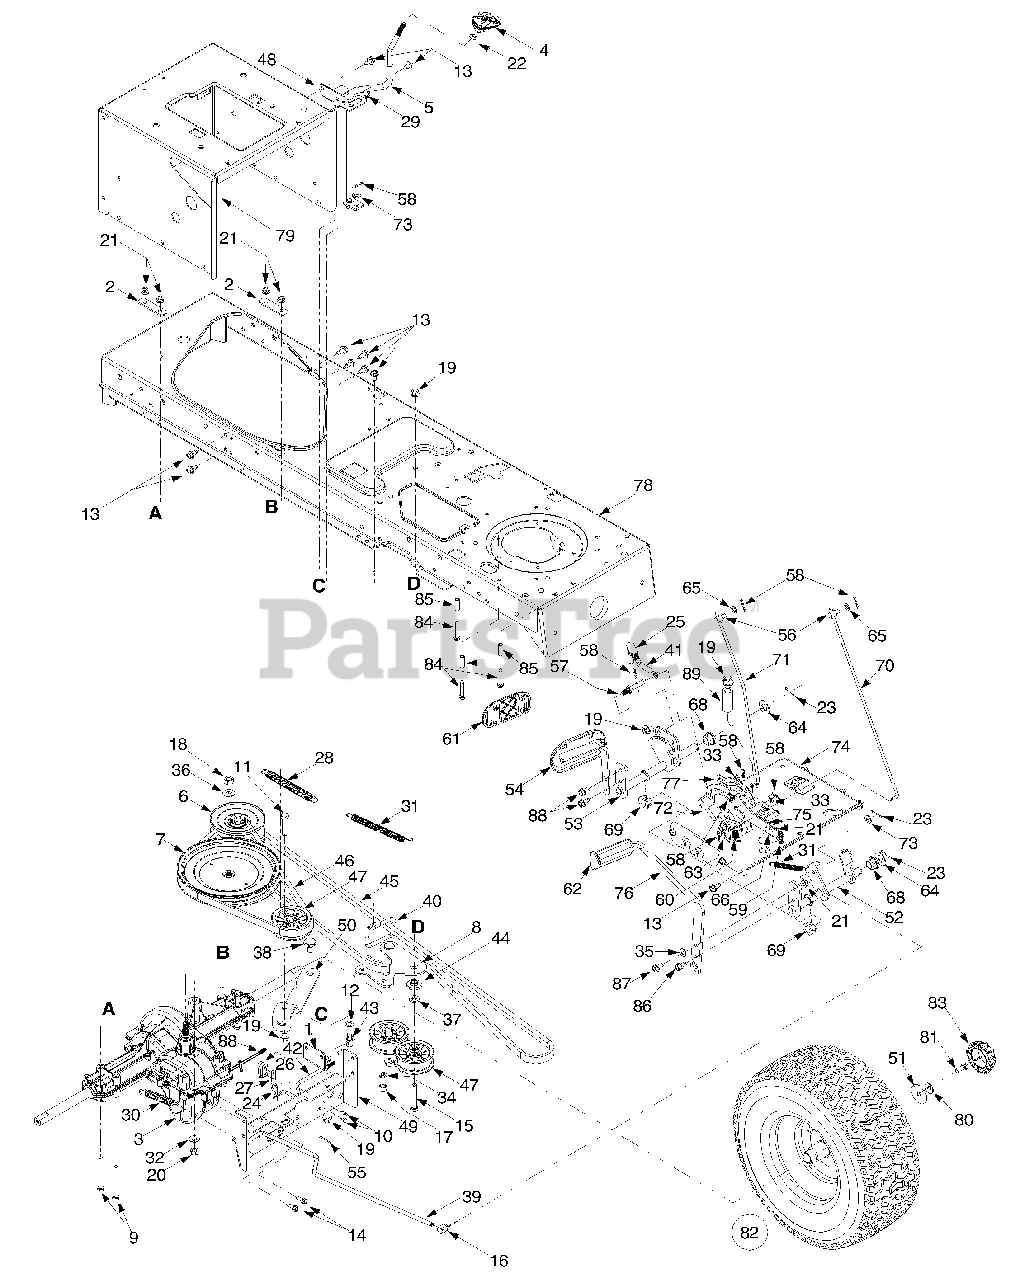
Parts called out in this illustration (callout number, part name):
1	Shift Lever Support
2	Transaxle Mounting Bracket
3	Single-speed Transmission Assembly
4	Shifter Knob
5	Shift Lever
6	Variable-speed Pulley Assembly
7	Transmission Pulley, 8.5 x .5-36
7	Pulley Hub
8	Double-idler Bracket
9	Hex Cap Screw, 5/16-18 x 2.75
10	Self-tapping Screw, #8-18 x .5
11	Hex Cap Screw, 3/8-16 x 1.75
12	Flat Washer, .51 x 1.0 x .060
13	Self-tapping Screw, 5/16-18 x .625
14	Self-tapping Screw, 1/4-20 x .75
15	Hex Cap Screw, 3/8-16 x 2.25
16	Ferrule, 5/16-18
17	Hex Nut, 3/8-24
18	Hex Nut, 7/16-20
19	Flange Lock Nut, 3/8-16
20	Hex Nut, 3/8-16
21	Flange Lock Nut, 5/16-18
22	Jam Nut, 3/8-16
23	Cotter Pin
24	Internal Cotter Pin
25	Ball Joint
26	Short Spring Switch
27	Insulator Nut Plate
28	Extension Spring, .62 Dia. x 6.12
29	Compression Spring Clip
30	Extension Spring, .59 OD x 4
31	Extension Spring, .50 Dia. x 6.37
32	Bell Washer, .401 x .87 x .063
33	Flat Washer, .385 x .62 x .063
34	Lock Washer, 3/8
35	Flat Washer, .344 x .750 x .120
36	Bell Washer, .45 x 1.0 x .602
37	Flat Washer, .407 x .812 x .135
38	Shoulder Screw, .625 x .217
39	Brake Rod
40	Belt Guard
41	Idler Adjustment Rod, 3/8
42	Shift Rod
43	Adjustment Ferrule, 1/4-20 x 1.0
44	Shoulder Spacer, .38 ID
45	Lower Drive Belt
46	Upper Drive Belt
47	Flat Idler, 2.75 OD
48	Speed Control Rod Bracket
50	Idler Bracket
51	Flat Washer, .350 x 1.59 x .062
52	Brake Control Assembly
53	Speed Control Assembly
54	Drive Pedal Assembly
55	Cotter Pin, 1/8 x 1.25
56	Ferrule, 1/4-20
57	Pin, 3/8-16 x 2.43
58	Cotter Pin
59	Compression Spring, .34 OD x 1.0
60	Extension Spring, .50 OD x 1.41
61	Drive Pedal Pad
62	Brake Pedal Pad
63	Flat Washer, .281 x .5 x .063
64	Flat Washer, .64 x 1.24 x .06
65	Flat Washer, .344 x .062 x .03
66	Shoulder Screw, .437 x 1.62
67	Shoulder Screw, .5 x .434
68	Hex Flange Bearing
69	Split Hex Flange Bearing
70	Cruise Control Rod
71	Brake Lock Control Rod
72	Cruise Latch
73	Flat Washer, .344 x .688 x .065
74	Stearing Support Bracket
75	Drive Lock-out Bracket
81	Hex Cap Screw, 5/16-24 x .75
83	Hub Cap
84	Self-tapping Screw, 1/4-20 x 1.25
85	Spacer
86	Self-tapping Screw, 5/16-18 x .875
87	Self-tapping Screw, 5/16-18 x .75
88	Shift Rod
